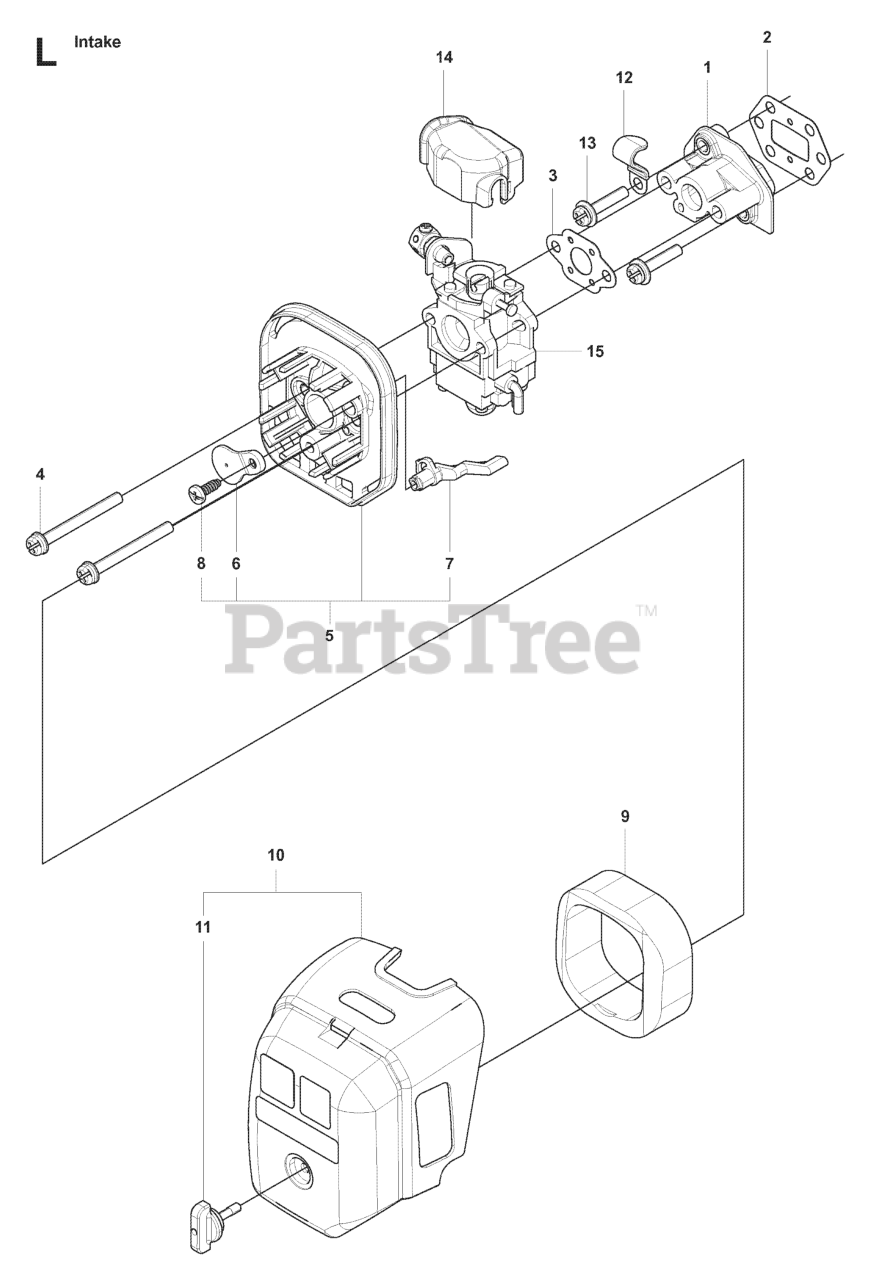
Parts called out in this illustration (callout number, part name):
1	INSULATOR
5	BODY ASSY.
6	PLATE, CHOKE
7	LEVER.CHOKE
